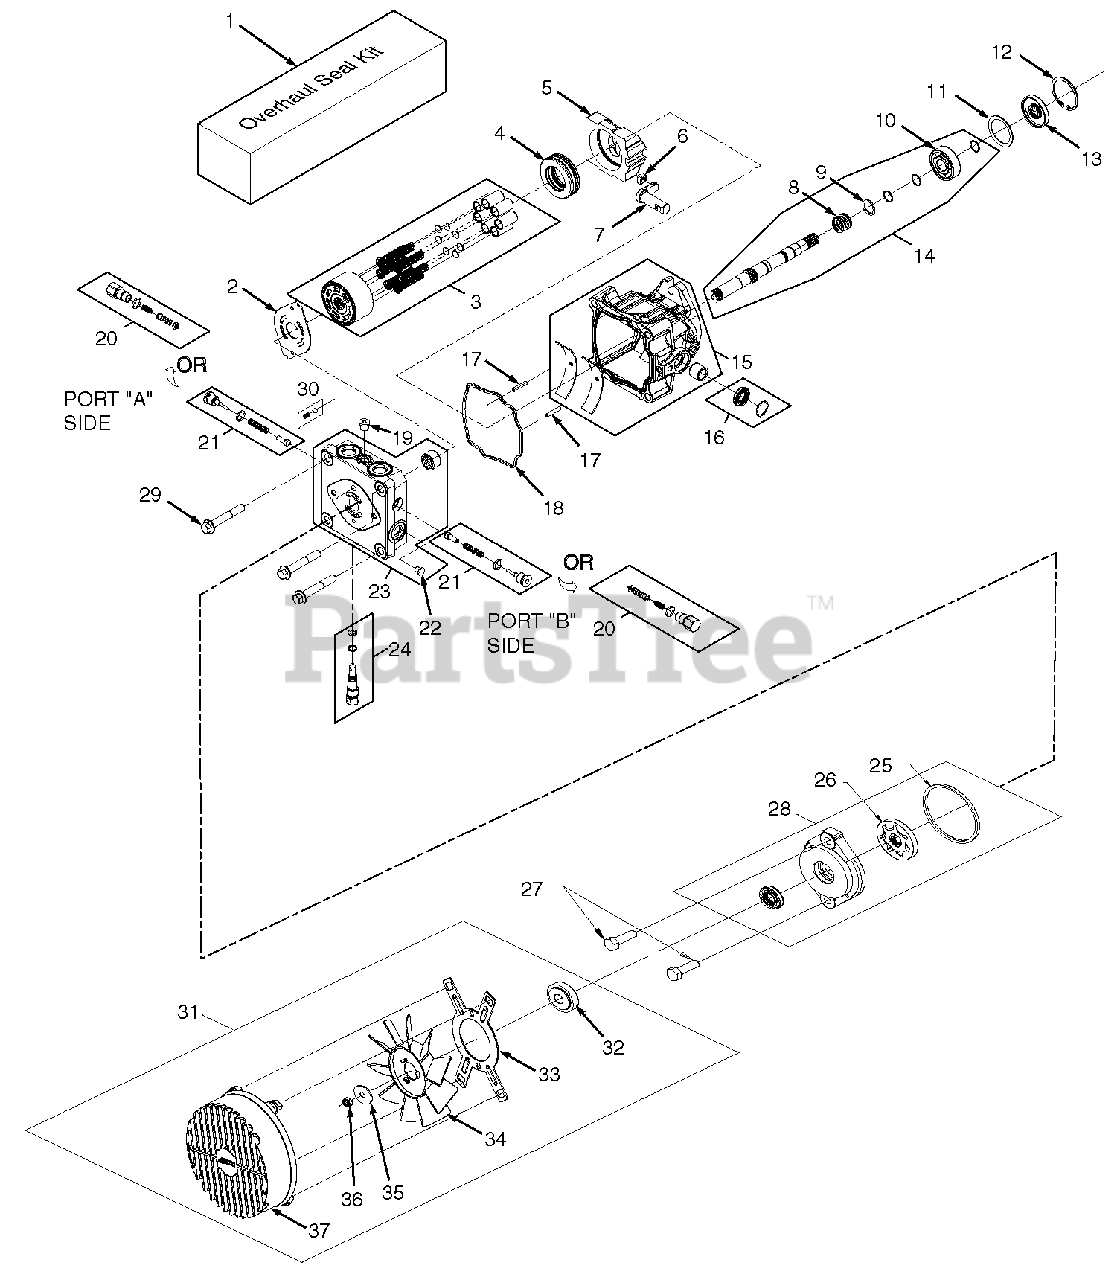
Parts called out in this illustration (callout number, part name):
1	Overhaul Seal Kit
2	Valve Plate
3	Cylinder Block Kit - 16cc
4	Thrust Ball Bearing Assembly
5	Variable Swashplate
6	Slot Guide
7	Trunnion Arm
8	Block Spring
9	Block Thrust Washer
10	Shaft Ball Bearing
12	Retaining Ring
14	Kit, Pump Shaft
15	Housing Kit
16	Trunnion Seal Kit
18	O-Ring
19	Straight Thread Plug
20	Shock Valve Kit
21	Shock Valve Kit
22	Straight Thread Plug
23	End Cap Kit
24	Bypass Valve Kit
26	Gerotor Assembly
27	Socket Head Cap Screw
28	Charge Pump Kit
29	Hex Screw, Flanged Head
30	Charge Relief Kit
31	Fan Kit
33	Bracket, Shroud
35	Washer
37	Shroud
